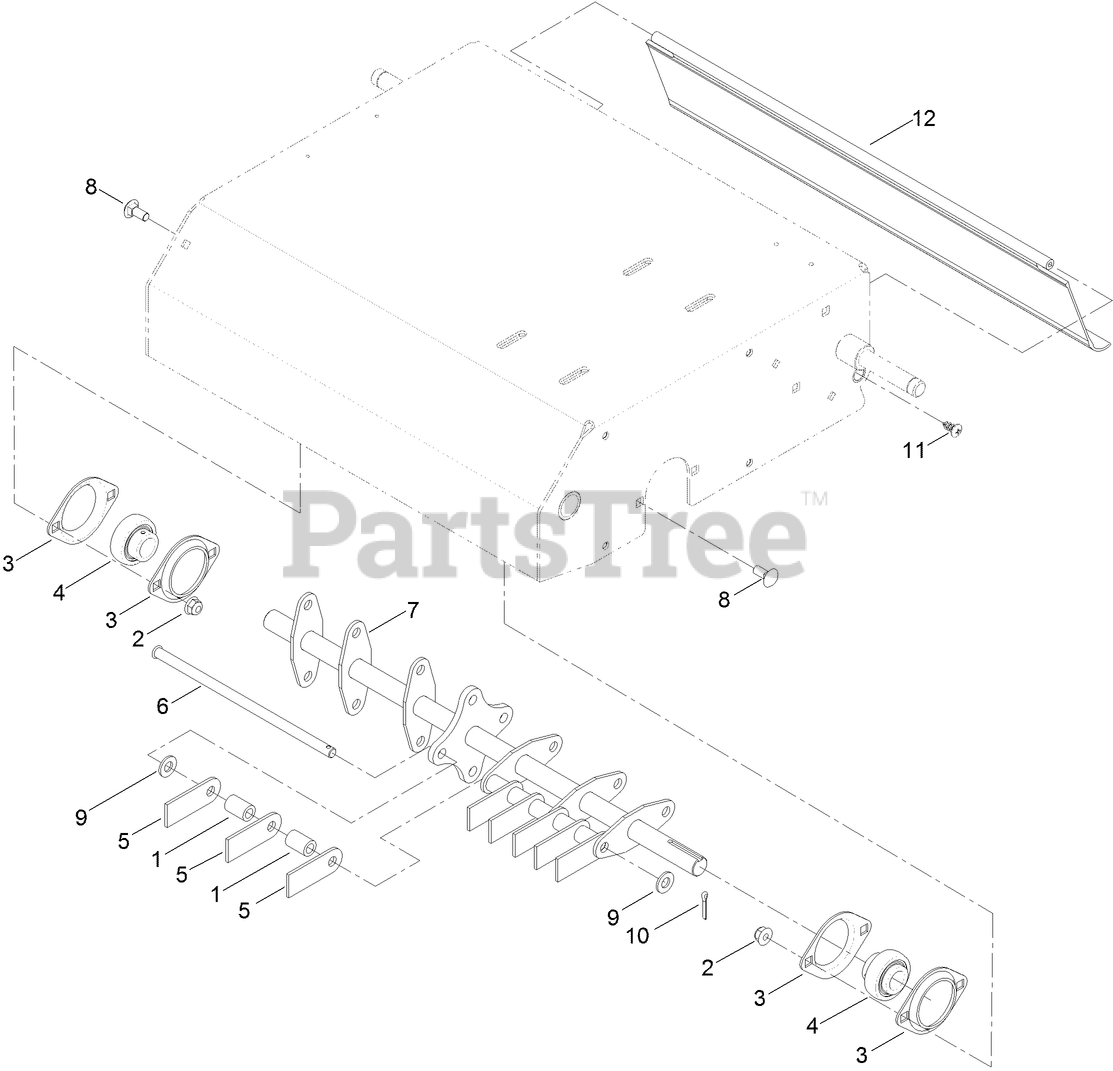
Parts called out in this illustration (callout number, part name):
1	SPACER
2	NUT-HF, NI
3	FLANGE-BEARING
4	BEARING-RACE, EXTENDED
5	BLADE-FLAIL
6	SHAFT-SATELLITE
7	SHAFT-RAKE
8	BOLT-CARR
9	WASHER-FLAT
10	PIN-COTTER
11	SCREW-PTH
12	SHIELD-TRAILING
